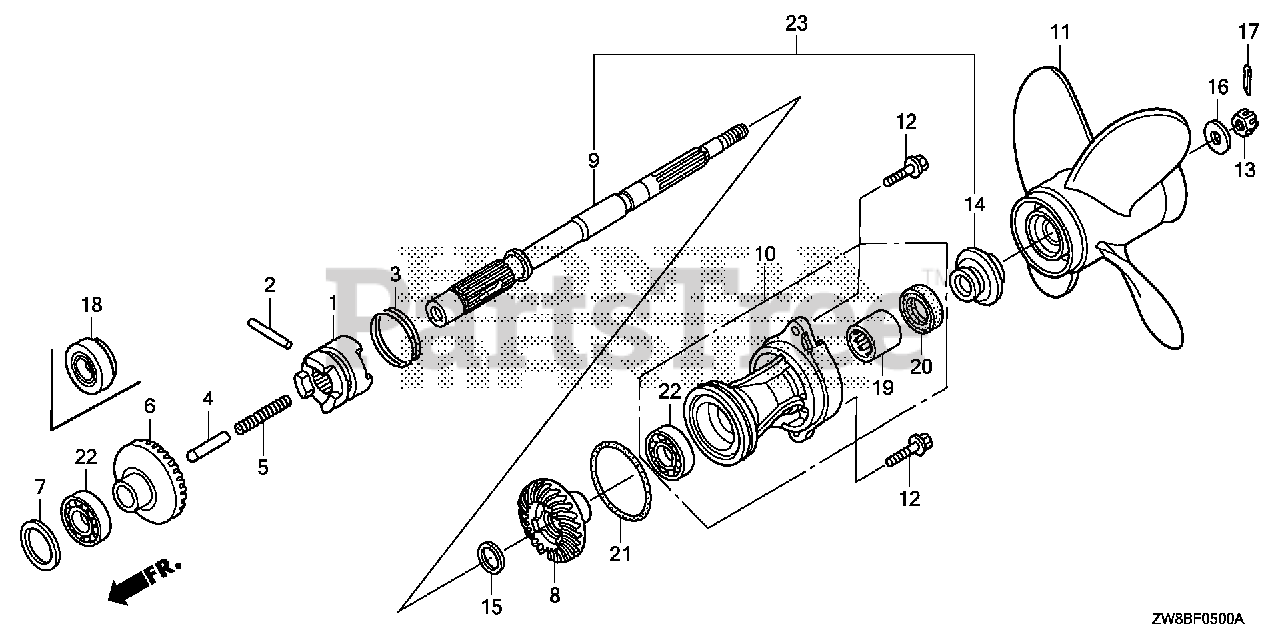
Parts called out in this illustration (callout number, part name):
1	SHIFTER, CLUTCH
2	ROLLER (4X29.8)
2	PIN, SHIFTER (4X30)
3	RING, CROSS PIN
4	SLIDER, SHIFT
5	SPRING, SHIFT
6	GEAR, FR. BEVEL
7	SHIM A (40MM)
7	SHIM B (40MM)
7	SHIM C (40MM)
7	SHIM D (40MM)
8	GEAR, RR. BEVEL
10	HOLDER ASSY., PROPELLER SHAFT *NH282MU* (OYSTER SILVER METALLIC-U)
11	PROPELLER, FOUR BLADES (10X6-1/2 HT) *NH283* (STIN GRAY)
11	PROPELLER, FOUR BLADES (9-1/4X7) *NH283* (STIN GRAY)
11	PROPELLER, FOUR BLADES (9-1/4X8) *NH283* (STIN GRAY)
11	PROPELLER, FOUR BLADES (9-1/4X9) *NH283* (STIN GRAY)
11	PROPELLER, FOUR BLADES (9-1/4X10) *NH283* (STIN GRAY)
12	BOLT, FLANGE (6X20)
13	NUT, CASTLE (10MM)
14	WASHER, PROPELLER THRUST
15	WASHER (18MM)
16	WASHER (10MM)
17	PIN, SPLIT (3MM)
18	BEARING, RADIAL BALL (25X47X12)
18	BEARING (25X47X15)
19	BEARING, NEEDLE (17X24X20) (NTN)
20	SEAL, WATER (17MM)
21	O-RING (59.4X3.1)
22	BEARING, RADIAL BALL (25X47X12)
22	BEARING, RADIAL BALL (6005)
23	SHAFT KIT, PROPELLER
